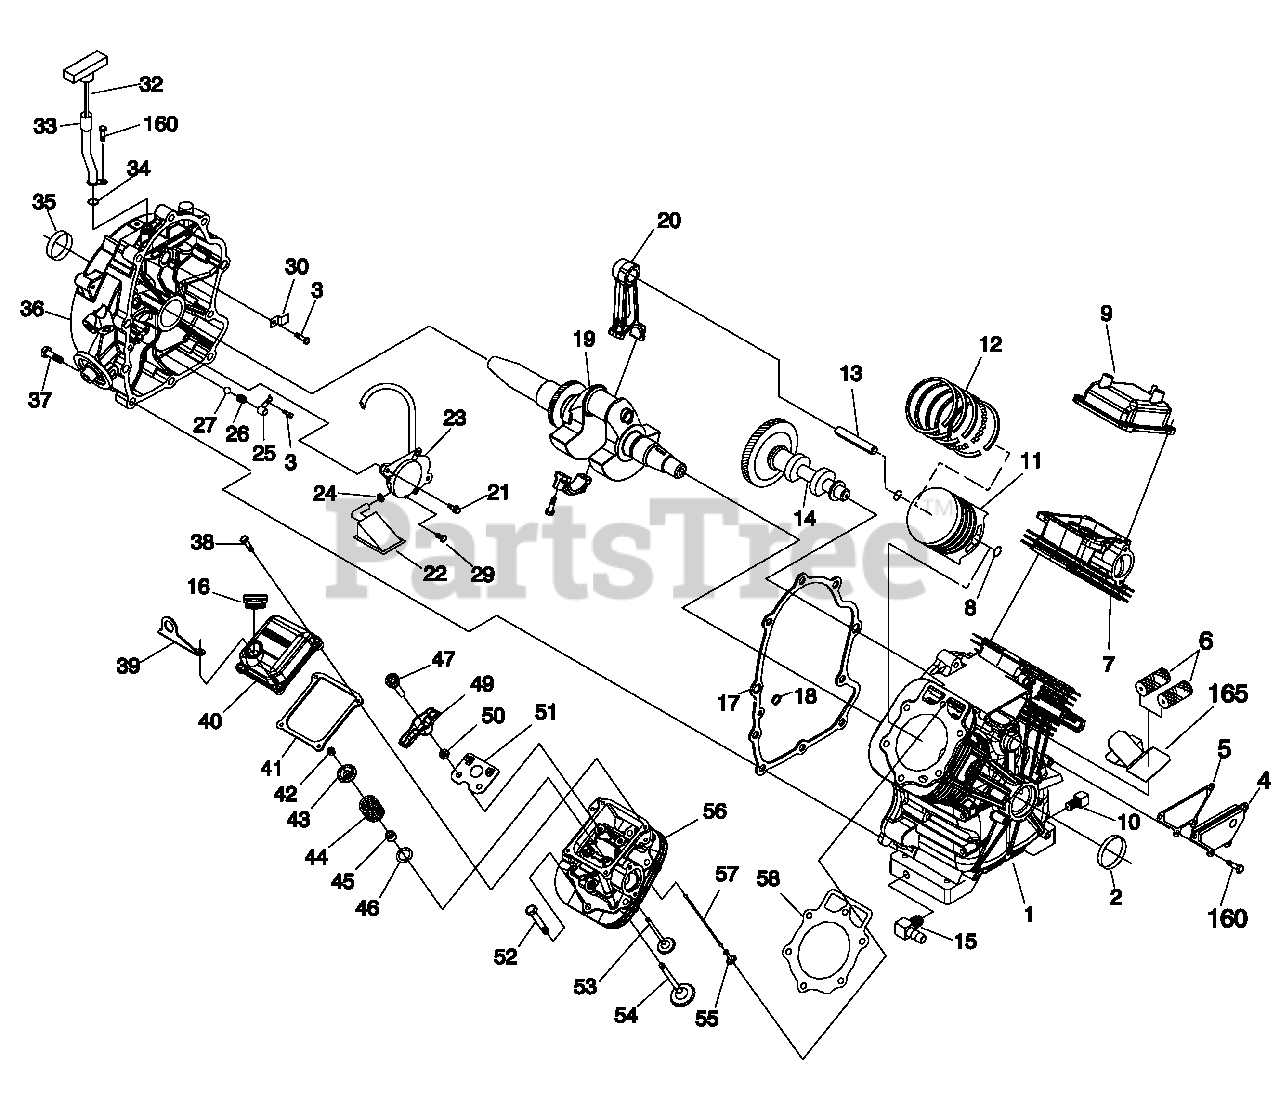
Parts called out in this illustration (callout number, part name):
1	ASSY, CRANKCASE WITH SLEEVE
2	SEAL, 38 I.D. CRANKSHAFT GREEN
3	SCREW, HHFCS M6-1.0 X 12 G8.8
4	ASSEMBLY, BREATHER DUAL VALVE
5	GASKET, BREATHER COVER
6	SEPARATOR, OIL BREATHER
7	ASSEMBLY, HEAD #1
8	RETAINER, PISTON PIN 20
9	ASSY, ROCKER COVER W/BARB
10	PLUG,STD PIPE 3/8" STEEL SQ HEAD
11	PISTON, DISH TOP DIA 90 COATED
12	RING SET, PISTON TOP DIA 90
13	PIN PISTON
14	ASSEMBLY, CAMSHAFT & GEAR
15	BARBED ELBOW, 90 DEG. 3/8NPT X 3/8 VS
16	ASSEMBLY, OIL FILL CAP
17	GASKET, CRANK CASE
18	SEAL, OIL PASSAGE
19	CRANKSHAFT AND GEAR GTH-990
20	ASSEMBLY, CONNECTING ROD GT-990
21	SCREW SHC SEMS M6-1.0 X 50 G8.8
22	SCREEN, OIL PICKUP
23	ASSY,OIL PUMP GTH W/O O-RING
24	O-RING, 0.49 ID X 0.07 THICK
25	COVER, OIL RELIEF
26	SPRING, OIL RELIEF
27	BALL, 1/2D OIL RELIEF
29	SCREW, PLASTITE HI-LOW #10
30	CLAMP, OIL TUBE
32	ASSEMBLY, DIPSTICK GTH-990 PORTABLE
33	TUBE, DIPSTICK
34	O-RING, 3/8 X 1/2
35	SEAL, 42 I.D. CRANKSHAFT GREEN
36	GEARCOVER / ADAPTOR GTH990/760
37	SCREW, HHFC M10-1.5 X 55
38	SCREW HHFC M6-1.0 X 25
39	LIFT HOOK, GT990/760
40	COVER, ROCKER W/OIL FILL “GENERAC" TEXT
41	GASKET, VALVE COVER
42	KEEPER, VALVE SPRING
43	RETAINER, VALVE SPRING
44	SPRING, VALVE
45	SEAL, VALVE STEM D7
46	WASHER, VALVE SPRING
47	STUD, ROCKER ARM PIVOT
49	ROCKER ARM
50	NUT, HEX M8-1.0 GB YELLOW CHROM
51	PLATE, PUSH ROD GUIDE
52	SCREW HHFC M8-1.25 X 65
53	VALVE, EXHAUST
54	VALVE, INTAKE
55	TAPPET, SOLID
56	ASSEMBLY, HEAD #2
57	PUSHROD 147
58	GASKET, HEAD
60	KIT GEAR COVER
61	KIT GASKET
62	KIT PISTON & RINGS
63	KIT BREATHER ASSEMBLY
64	KIT HEAD ASSEMBLY CYLINDER 1
65	KIT HEAD ASSEMBLY CYLINDER 2
65	DIVERTER, BREATHER GTH
66	KIT OIL RELIEF
